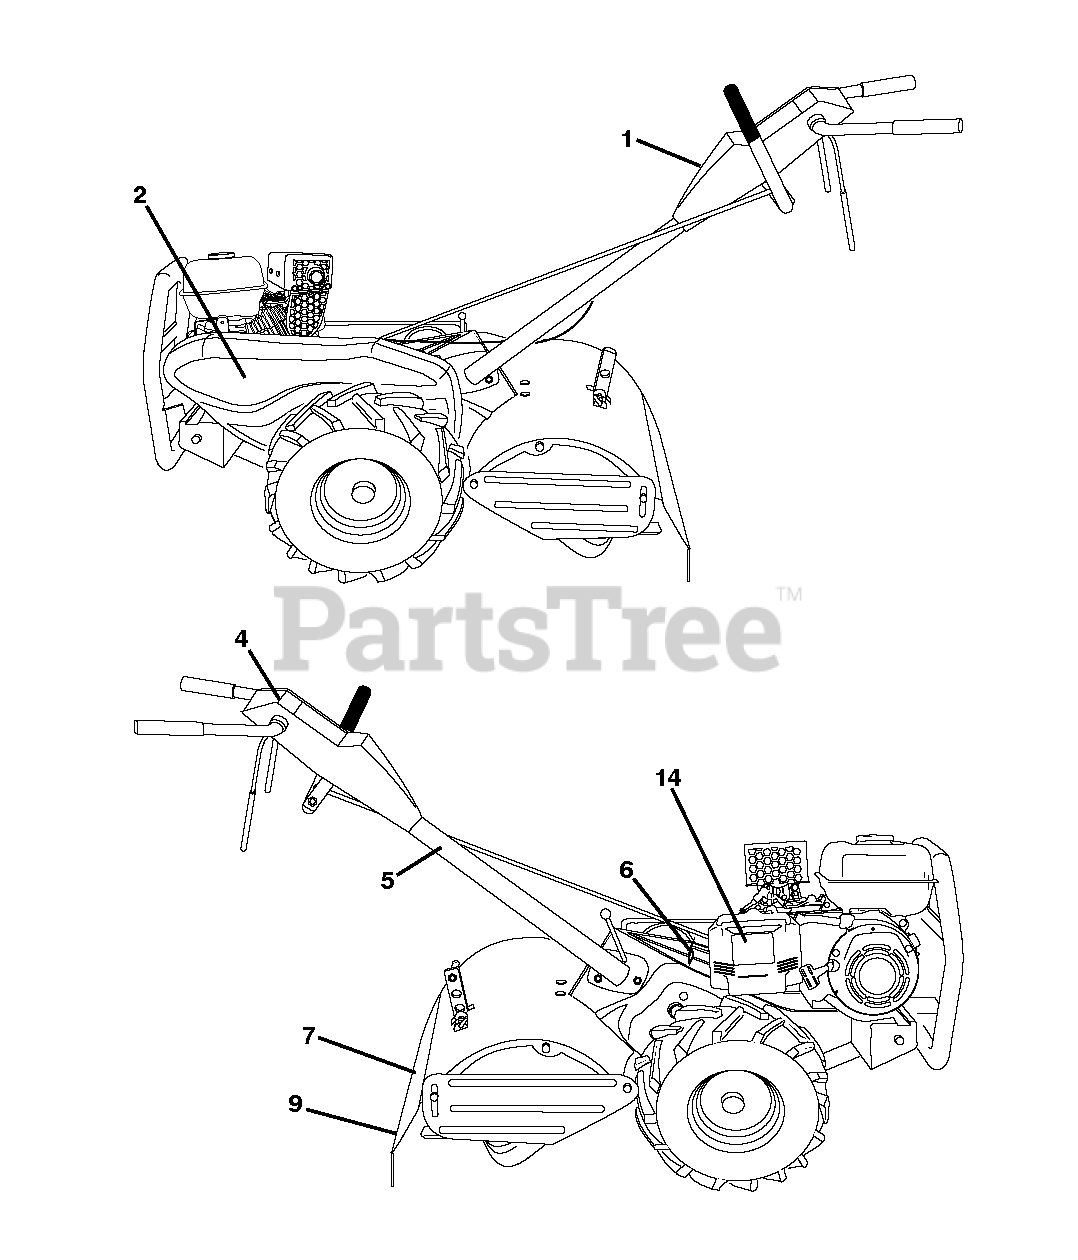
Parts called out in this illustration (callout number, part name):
4	DECAL.CNTRL.PNL.OPER.ENG/FR
5	DECAL TI
6	DECAL.SHIFT.INDICATOR.TILLER
7	DECAL WARNING
